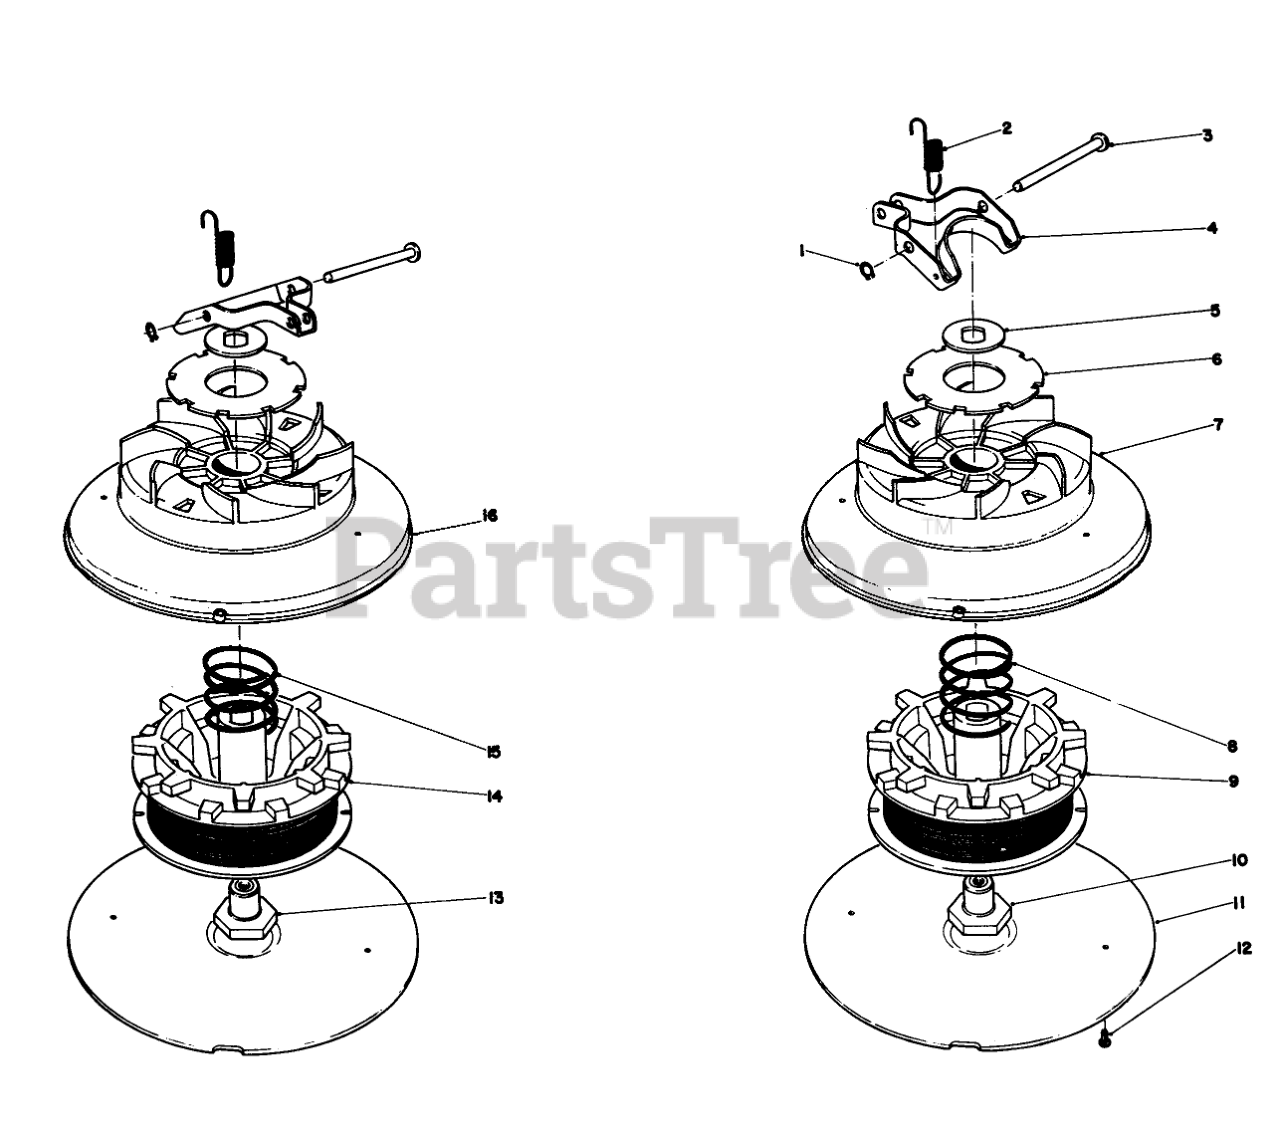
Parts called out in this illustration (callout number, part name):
1	Retaining Ring
2	Spring-Fork
3	Pivot Pin
4	Indexing Fork
5	WASHER
6	Thrust Washer
7	Drum L.H. (Incl. Ref. #6)
8	COMP SPRING
9	Spool L.H.
10	LH RET NUT
11	DRUM COVER
12	Screw
13	Nut Retaining R.H.
14	Spool R.H.
15	Spring R.H.
16	Drum R.H. (Incl. Ref. #6)
